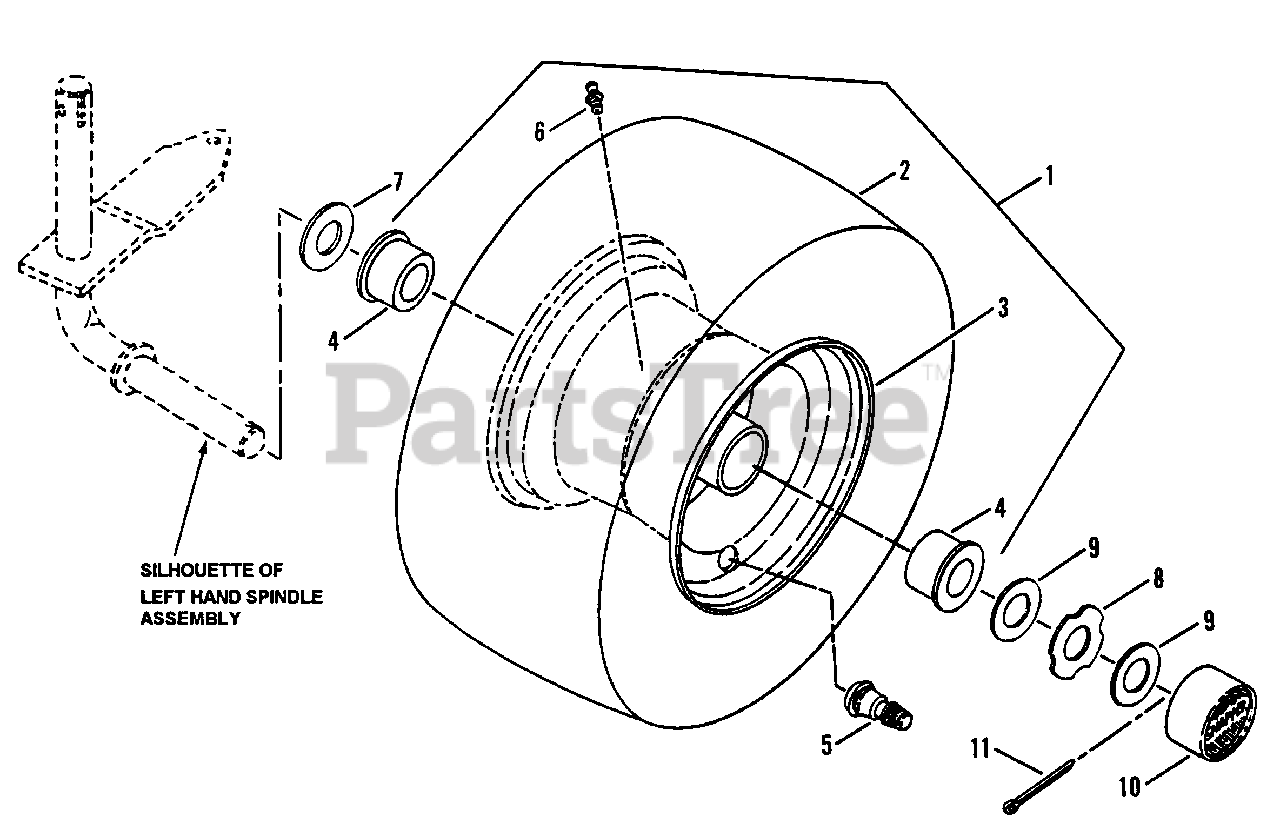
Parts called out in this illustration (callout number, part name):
1	ASSEMBLY, Front Tire & Rim, 38 & 42 Decks
2	TIRE, 15 x 6.00
3	Rl M, 5-1/2 x 4.00
4	BEARING, Wheel
5	VALVE, Air (Snap-In)
6	FITTING, Lube 1/4-28 Tapered Thread
7	WASHER, Flat, 5/32 x 25/32 I.D. x 1-1/2 O.D.
8	WASHER, Hub-Cap Retaining
9	WASHER, Flat, 1/16 x 49/64 1.9. x 1-5/16" O.D.
10	HUB-CAP
11	COTTER-PIN, 5/32 x 1
